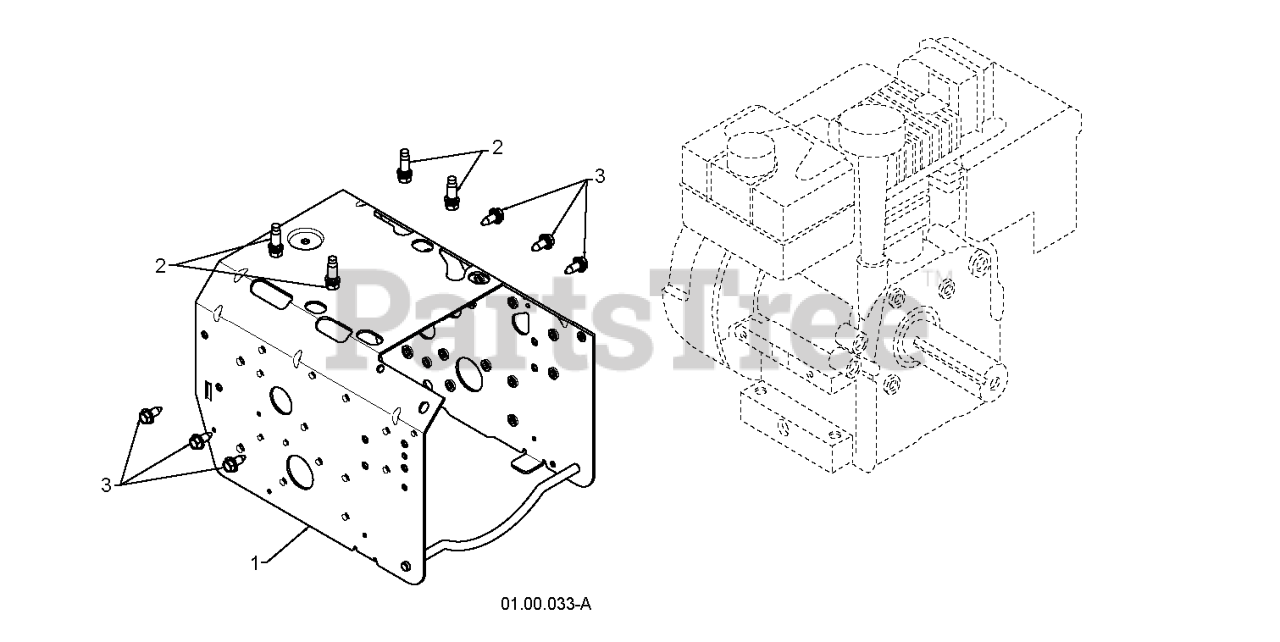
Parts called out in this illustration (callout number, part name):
1	FRAME.WELD.PNT.GEAR.ORANGE
2	BOLT 3/8-16X1-1/8
3	BOLT.HEX.HD.WASHER.5/16-18X.75
